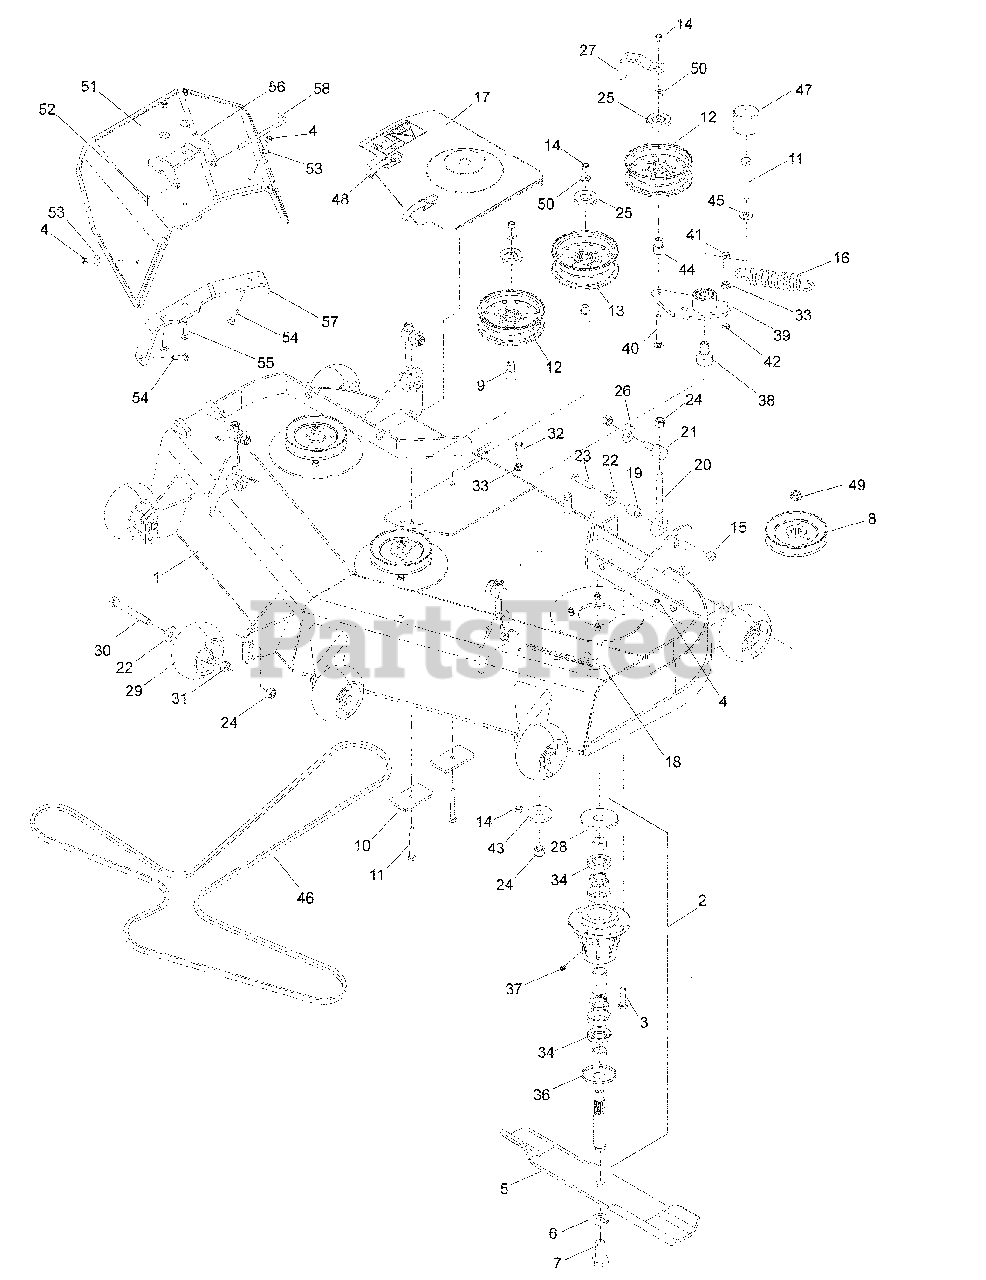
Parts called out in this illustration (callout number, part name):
1	DECK w/DECALS
2	SPINDLE
3	HCS 5/16-18 x 1¼
4	NUT 5/16-18 HEX NYLOC
5	BLADE, 18"
6	WASHER 5/8 SPLIT LOCK
7	HCS 5/8-18 x 1¼
9	BUSHING, IDLER
10	PAD
11	HCS ½-13 x 3¼
12	PULLEY, IDLER
13	PULLEY, IDLER (WIDE)
14	NUT 3/8-16 HEX NYLOC
15	NUT 7/16-14 HEX CTRLK GR A
17	BELT SHIELD ASSM RT
18	DECAL, TUNNELRAM
22	WASHER ½ SPRING
23	HCS 7/16-14 x 1¾
24	NUT ½-13 HEX NYLOC
25	SHIELD, DUST
27	GUIDE, BELT
28	DUST CAP, TOP
29	WHEEL, GAUGE
30	HHB ½-13 x 4
31	NUT ½-13 HEX
32	HCS 3/8-16 x 1¼
33	NUT 3/8-16 HEX WHIZLK
34	SEAL, SHAFT
35	DUST CAP, BOTTOM
36	GREASE POPPET
38	BEARING, PIVOT
39	ARM, IDLER w/BEARINGS
40	RHSNB 3/8-16 x 2¾
41	HCS 3/8-16 x 1½ GR8
42	NUT 3/8-16 HEX JAM
43	WASHER, SUPPORT
44	BUSHING, IDLER
45	WASHER ½ BELLEVILLE
46	BELT, DECK
47	CAP, VINYL
48	DRAW LATCH
49	NUT ¾-16 FLANGE
50	WASHER 3/8 THICK
51	CHUTE, DISCHARGE
52	PIN, COTTER 1/8 x ¾
53	WASHER 5/16 STD FLT
54	RHSNB 5/16-18 x 1¼
55	RHSNB 5/16-18 x 1½
56	BRACKET, CHUTE
57	REINFORCEMENT, BRKT
58	PIN, CLEVIS
